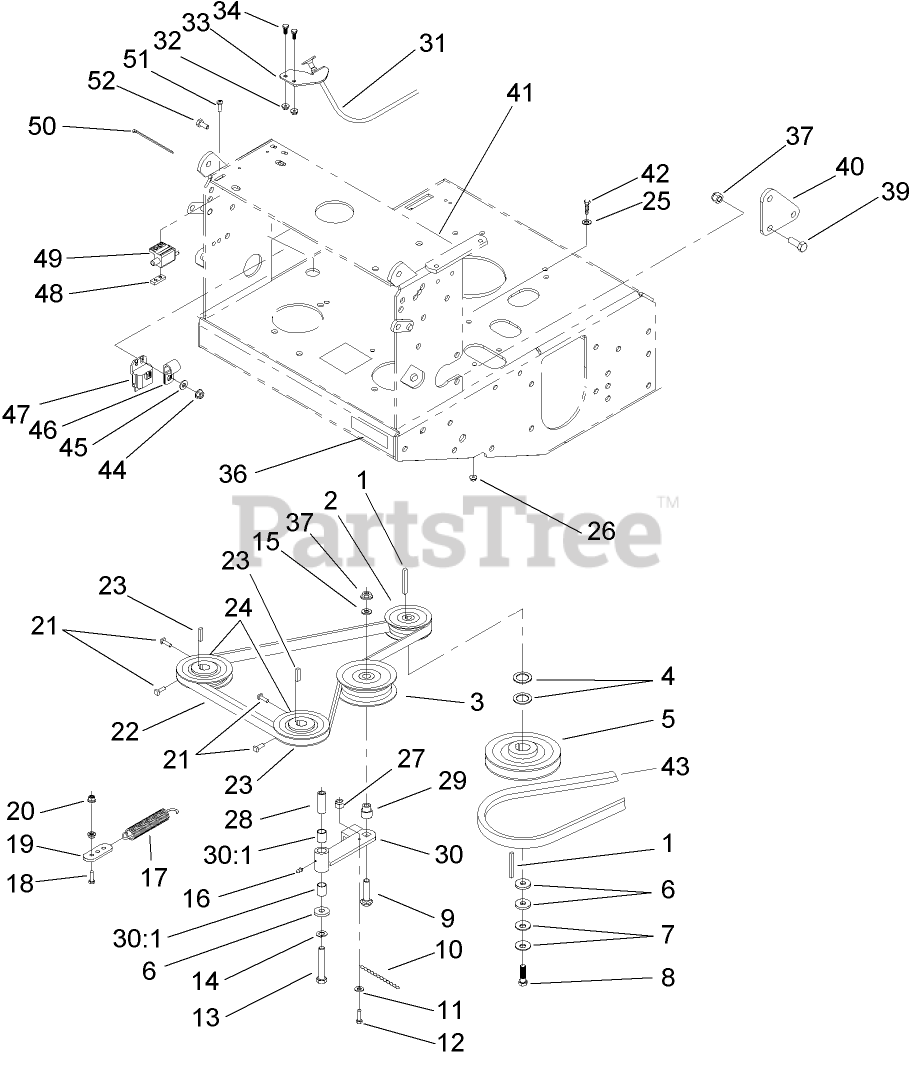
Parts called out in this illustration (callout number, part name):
2	PULLEY
3	PULLEY-IDLER
4	WASHER-SPACER
5	PULLEY ASM
6	WASHER
7	WASHER-SPRING
8	SCREW-HH
9	SCREW-CARR
10	Chain-Link, Twist
11	WASHER-FLAT
12	SCREW-HSH
13	SCREW-HH
14	WASHER
15	SPACER
16	FITTING-GREASE
17	SPRING-EXTENSION
18	SCREW-HH
19	Anchor-Spring
20	NUT-HF
21	SCREW-SET
22	V-BELT
24	SHEAVE ASM
25	WASHER-FLAT
26	NUT-HHF, WHIZ
27	NUT-LOCK, NI
28	BUSHING
29	BUSHING-IDLER
30	Idler Arm ASM
30:1	SLEEVE-BEARING
31	Cable-Choke
32	NUT-HF
33	Bracket-Cable, Choke
34	SCREW-HH
36	DECAL-CAUTION
37	NUT-LOCK, NI
39	SCREW-HH
40	Bellcrank
41	DECAL-SHUT OFF, FUEL
42	SCREW-HH
43	BELT-V
44	NUT-LOCK, NI
45	WASHER-FLAT
46	CLIP-LOOM
47	MODULE-INTERLOCK
48	PLATE-TAPPED
49	SWITCH-OPEN, NORMALLY
50	TIE-CABLE
51	SCREW-PPH
52	SCREW-HH
